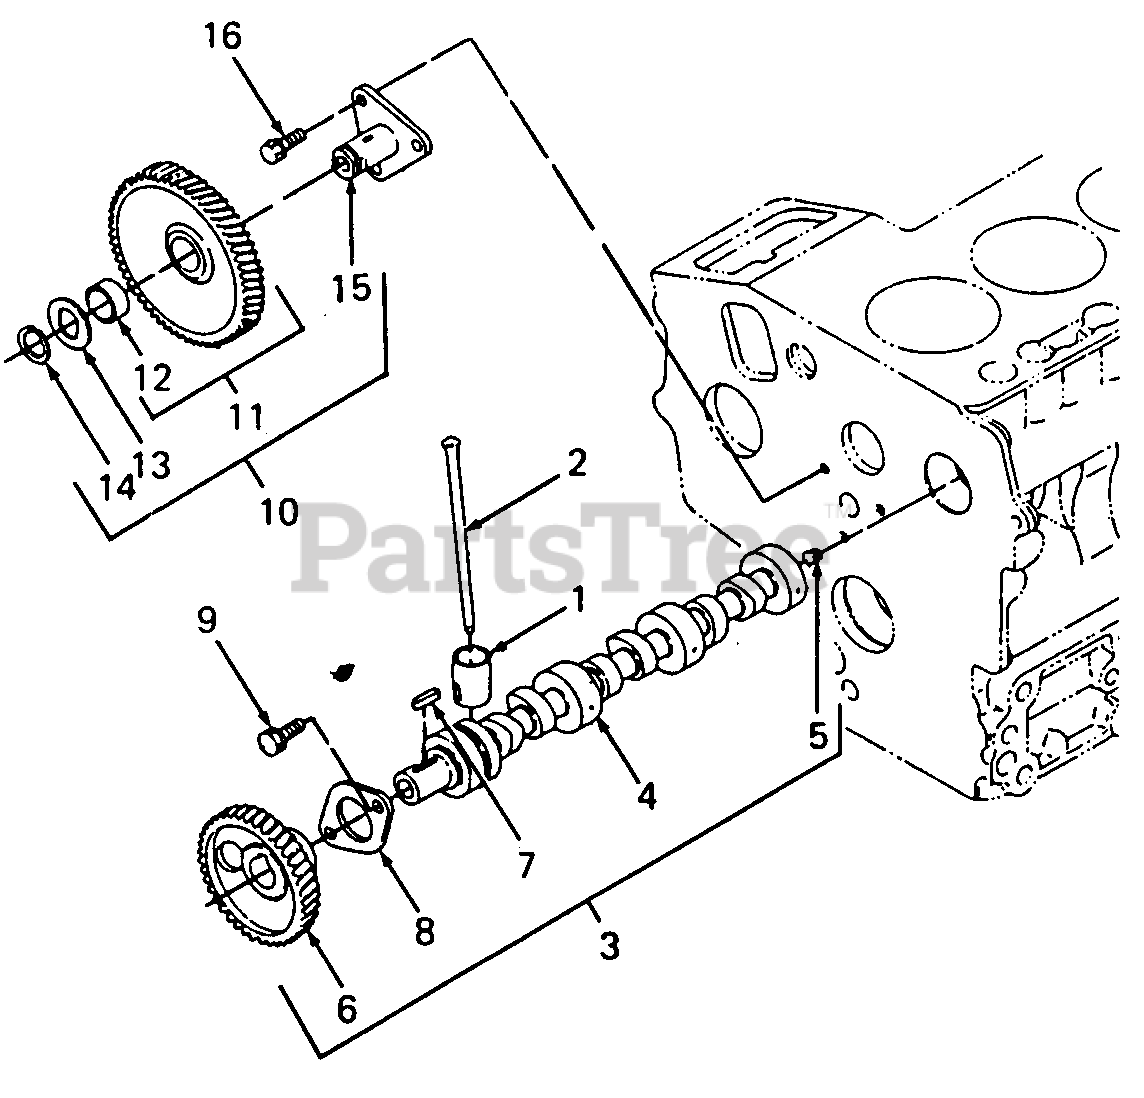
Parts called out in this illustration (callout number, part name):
3	Camshaft Assy
6	Gear, Camshaft
8	Stopper, Camshaft
10	Idle Gear Assy
13	Collar, Idle Gear 2
15	Shaft, Idle Gear
